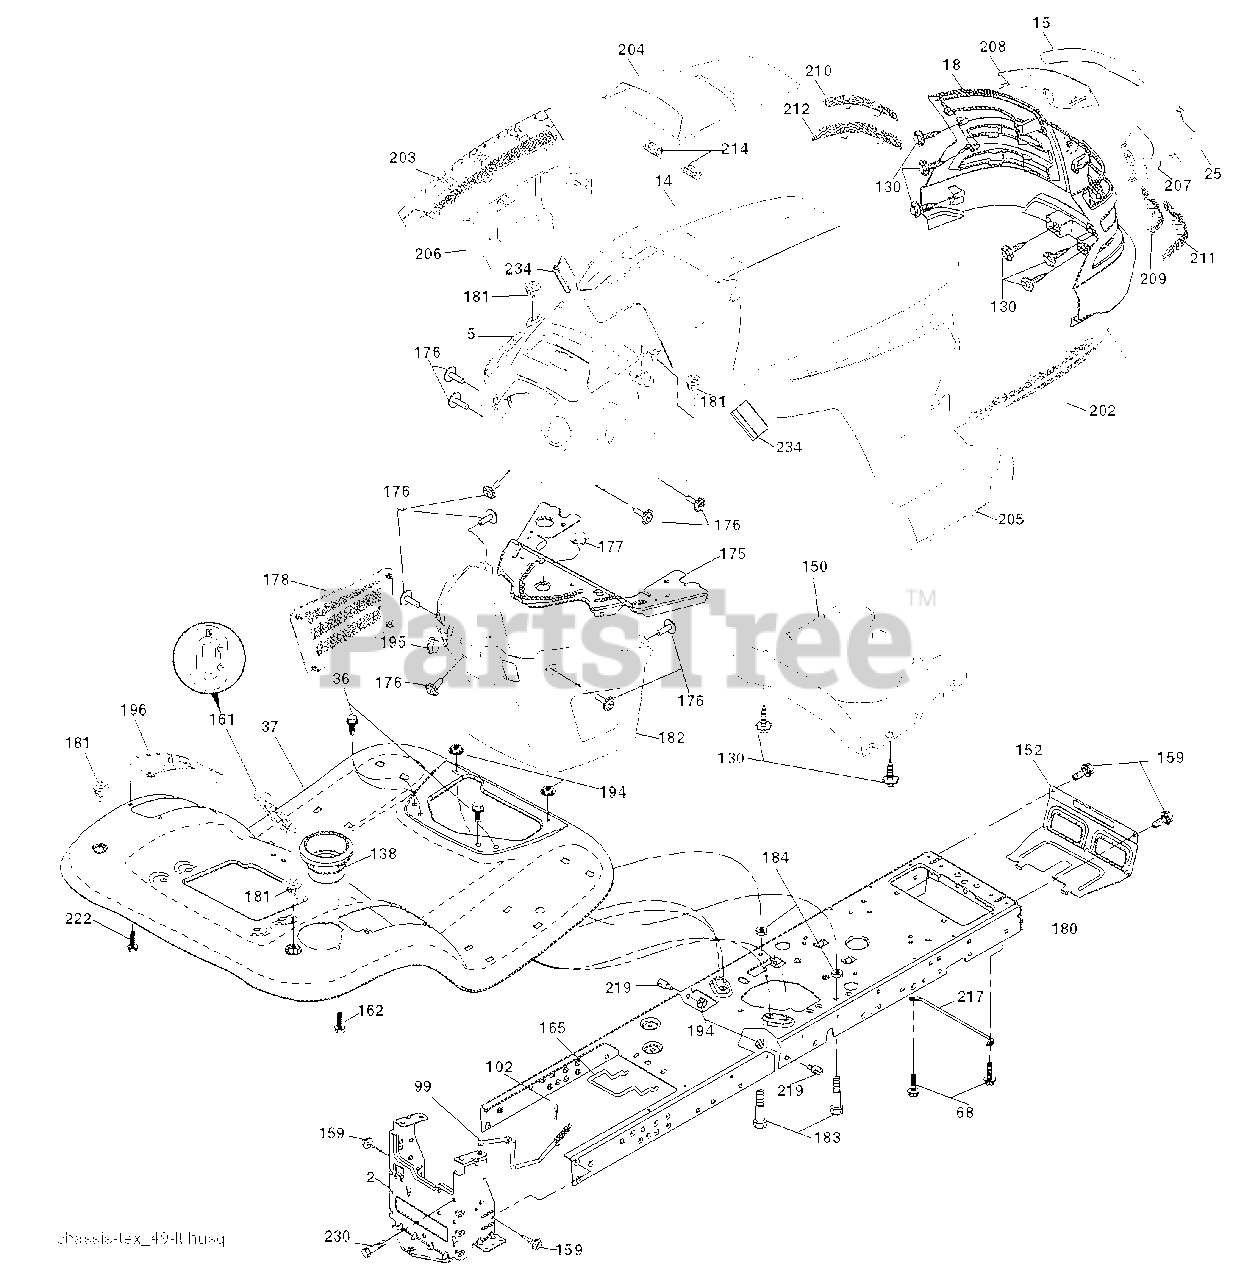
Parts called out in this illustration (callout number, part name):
5	Dash
14	Hood
18	Grille/Lens Asm.
36	Screw 5/16-18 x 3/4
68	Screw Thdrol 5/16-18 x 1/2
99	Rod Asm Bypass
102	Retainer Spring 1"
130	Screw 10 x 3/4 Single Lead-Hex
138	Cupholder
152	Shield Browning
159	Screw Hexwsh Thdr 3/8-16 x 3/4
161	Window Fuel
165	Support Tank Rear
175	Crossmember
176	Screw 10-24 x 5/8
177	Bushing Steering
178	Cargo Net Asm.
180	Chassis
181	Bushing Mtg. Fender Crgo
182	Dash Lower
183	Bolt Fin Hex 5/16-18 unc x 1-1/4
184	Spacer Fender
194	Nut Lock Hex Flange 5/16-18
195	Plug Hole Dash Lower
196	Console Asm. Deck Lift
197	Rod Pivot
202	Vent Side Hood RH
203	Vent Side Hood LH
204	Vent Top Hood
205	Skirt Hood Side RH
206	Skirt Hood Side LH
209	Insert Hex Top RH
210	Insert Hex Top Lh
211	Insert Hex Bottom RH
212	Insert Hex Bottom LH
214	Clip Retainer Tinner
219	Stud Fastner
222	Screw Thdrol 1/4-20 x 5/8
229	Screw 3/8-16 x 1
230	Bolt Shoulder 5/16-18
234	Bumper Hood Tex
